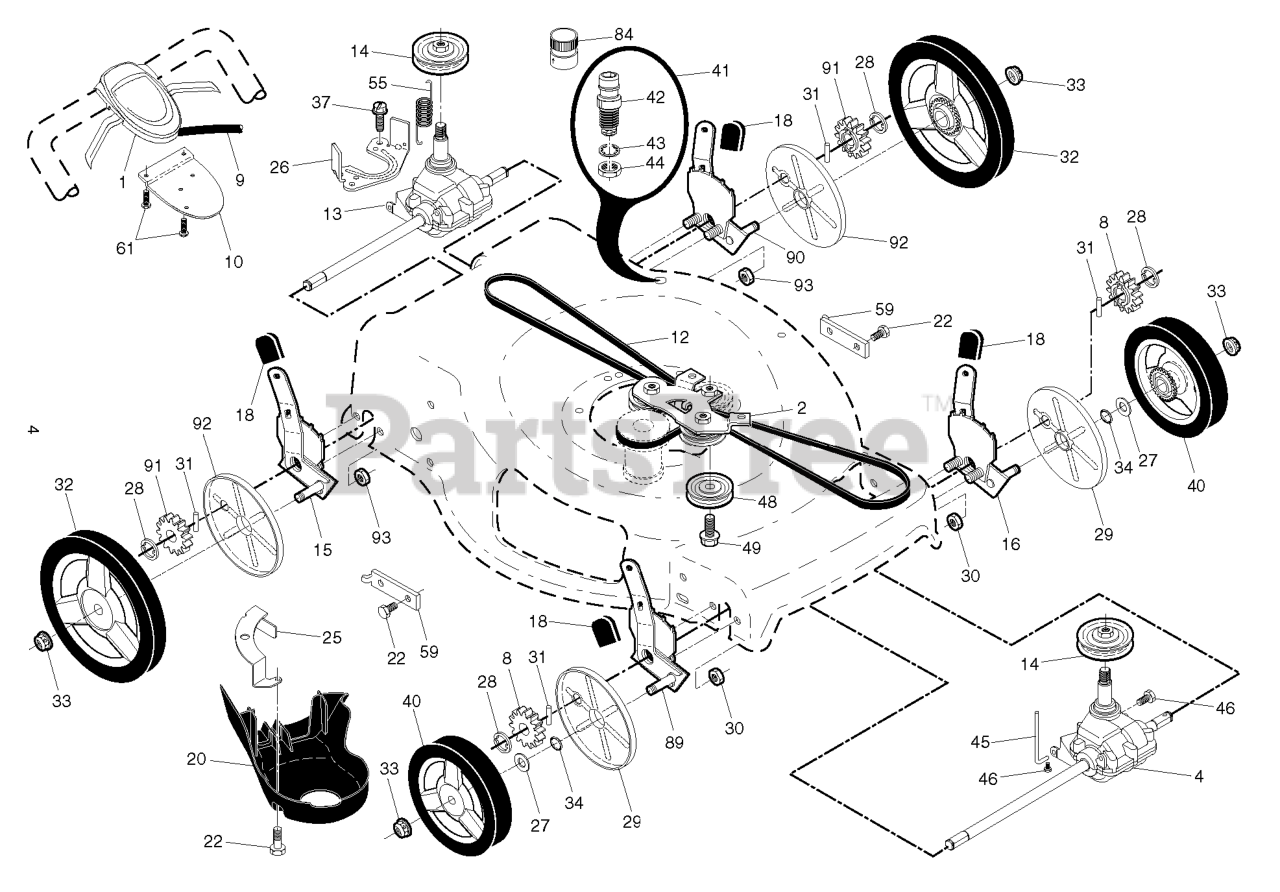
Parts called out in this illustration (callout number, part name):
1	CONTROL.AW2.22+RG.BS.GEN.BK/BK
2	BRACKET.ASM.AWD.BZP.BLACK
4	RP.TRANSMISSION.22+.AWD.FRONT
8	PINIION.14.TOOTH.RGD
9	CABLE.DRIVE.RWD.WALK.
10	BRACKET.DRIVE.CONTR.GEN2.BLACK
12	BELT.DRIVE.AWD.13 ZINC DUSTED
13	TRANMISSION.ASM.22+AWD.REAR.14
14	RP PULLEY.PM.22+AWD
15	ADJUSTER.ASM.HW.AWD.QK.RR.BLKZ
16	ADJUSTER.ASM.22+FGD.LF /AWD LT
18	SELECTOR KNOB
20	COVER.REAR.DRIVE.22+2013
22	BOLT.5/16HEX.WHS.HD
25	BRACKET.DRIVE.COVER.RGD.BZP
26	BRACKET.TRAN.BELTKEEPER.22+RGD
27	WASHER FLUT
28	E-RING 7/16 RE
29	COVER.DUST.WHEEL.INNER.WALK
30	NUT.FLANGE.1-4-20-SERR
31	PAWL, DRIVE
32	WHEEL.11.H3SP.AWD.BB.460.BU2
33	NUT.HEX.FLANGE.3/8-16.LO(3 2)
34	O-RING..070X.487.NEOPRENE
40	WHEEL.8".AWD.3SP.EXT.DR.GREY
41	KIT.WASH-OUT.PORT.ZINC.WALK
42	WASHOUT.PORT.ZINC.RGD.22+
43	WASHER.LOCK.INTERNAL.TOOTH
44	LOCKNUT.HEX.WITH.O-RING
45	BRACKET.AWD.FRONT.BELT.KEEPER
46	SCREW.HI-LO. 5/16 X 1.00
48	RP PULLEY.IDLER.ASM
55	SPRING.RETURN.AUTO.
59	BRACKET.SUPPORT.22+RWGD.BZP
61	SCREW, PHILLIPS HEAD 10 X 5/8
84	COUPLING.QUICK CONNECT
89	ADJUSTER.ASM.22+FGD.RF /AWD RT
90	ADJUSTER.ASM.HW.AWD.QK.LR.BZ
91	PINION.16.TEETH.HW.AWD.REAR
92	COVER.DUST.WHEEL.HW.AWD.REAR
93	NUT.HEX.FLANGE.1/4
